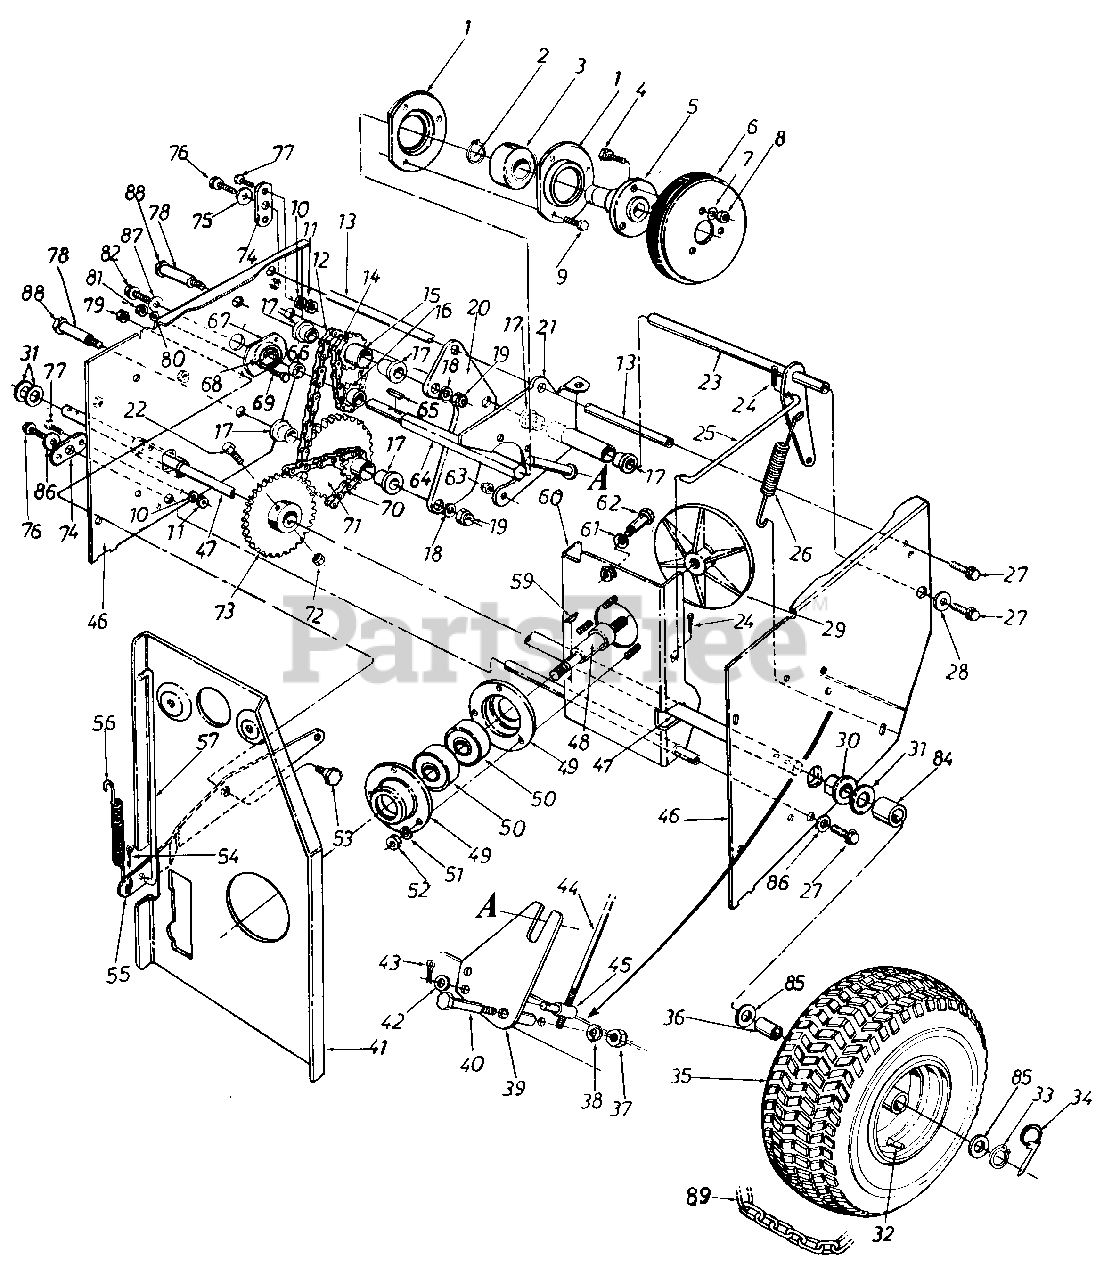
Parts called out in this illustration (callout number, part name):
1	Bearing Housing
2	Snap Ring-1.0" Dia.
3	Ball Brg. .25MM x 52MM x 15MM Thk.
4	Hex Sems Bolt 5/16-18 x .75" Lg.*
5	Friction Wheel Adapter
6	Friction Wheel Ass'y.
7	L-Wash. 5/16" I.D.
8	Hex Nut 5/16-18 Thd.
9	Hex Bolt 1/4-28 x .62" Lg.
10	L-Wash. 1/4" I.D.
11	Hex Nut 1/4-20 Thd.
12	#41 Chain-1/2" Pitch x 43 Links
13	Sliding Support Axle
14	#41 Chain-1/2" Pitch x 19 Links
15	9 and 14 Teeth Sprocket Hub Ass'y.
16	8 Teeth Sprocket
17	Flange Bearing .63" I.D.
18	L-Wash. 3/8" I.D.-H.D.
19	Hex L-Jam Nut 3/8-24 Thd.
22	Hex Bolt 1/4-28 x 1.5" Lg.
23	Drive Clutch Brkt. Ass'y.
24	Inter. Cot. Pin 5/16" Dia.*
25	Drive Clutch Rod .31" Dia. x 7.38" Lg.
26	Extension Spring 4.31" Lg.
27	Hex L-Bolt 5/16-18 x .62"
28	Fl-Wash. .345" I.D. x .75" O.D.
29	Aluminum Drive Plate
30	Flange Brg. w/Flats
31	Fl-Washer
32	Tubeless Air Valve
33	Snap Ring 3/4" Shaft
34	Klick Pin
35	Wheel Ass'y. Comp. 15 x 6
36	Bearing.75" I.D.
37	Hex Jam Nut 3/8-16 Thd.
38	L-Wash. 3/8" I.D.
41	Engine Brkt. Ass'y.
42	Fl-Wash. .344" I.D. x .62" O.D.
43	Cotter Pin 3/32" Dia. x .75" Lg.
44	Shifting Rod
45	Adjustment Ferrule
46	Frame Ass'y.
47	Free Wheeling Axle
48	Drive Plate Spindle
49	Bearing Housing
50	Ball Brg. .787" I.D. x 1.85" O.D.
51	L-Wash. 5/16" I.D.
52	Hex Nut 5/16-18 Thd.
53	Shld. Bolt .625" Dia. x .170" Lg.
54	Inter. Cotter Pin 5/16" Dia.
55	Auger Clutch Brkt.
56	Extension Spring .38" O.D. x3.18" Lg.
57	Auger Clutch Rod .31" Dia. x 10.62" Lg.
59	#61 Hi-Pro Key 3/16" x 518" Dia.
62	Shld. Bolt
63	Hex Ins. Jam Nut 1/4-28 Thd.
64	Hex Shaft
65	#9 Hi-Pro Key 3132" x 518" Dia.
66	Spacer .51" I.D. x .69" O.D.
67	Bearing Housing
68	Ball Bearing
69	Hex Bolt 1/4-20 x .62" Lg.
70	#420 Chain .50" Pitch x 29 Links
71	9 and 32 Teeth Sprocket Hub Ass'y.
72	Hex L-Nut 1/4-20 Thd.
73	22 Teeth Sprocket Hub Ass'y.
74	Pivot Axle Brkt.
75	Fl-Wash. .345" I.D. x .75"
76	Hex L-Bolt 5/16-18 x .62"
77	Hex Bolt 1/4-20 x .62" Lg.
78	Sprocket Hub Tubing 1.88"
79	Hex Cent. L-Nut 3/8-16 Thd.
80	L-Wash. 1/4" I.D.
81	Hex Nut 1/4-20 Thd.*
82	Hex L-Bolt 5/16-18 x .62"
84	Spacer.75" I.D.
85	Fl-Washer
86	Fl-Wash. .344" I.D. x .875"
87	Bell-Wash. .345" I.D. x .88"
88	Hex Bolt 3/8-24 x 2.75" Lg.
89	Tire Chain
